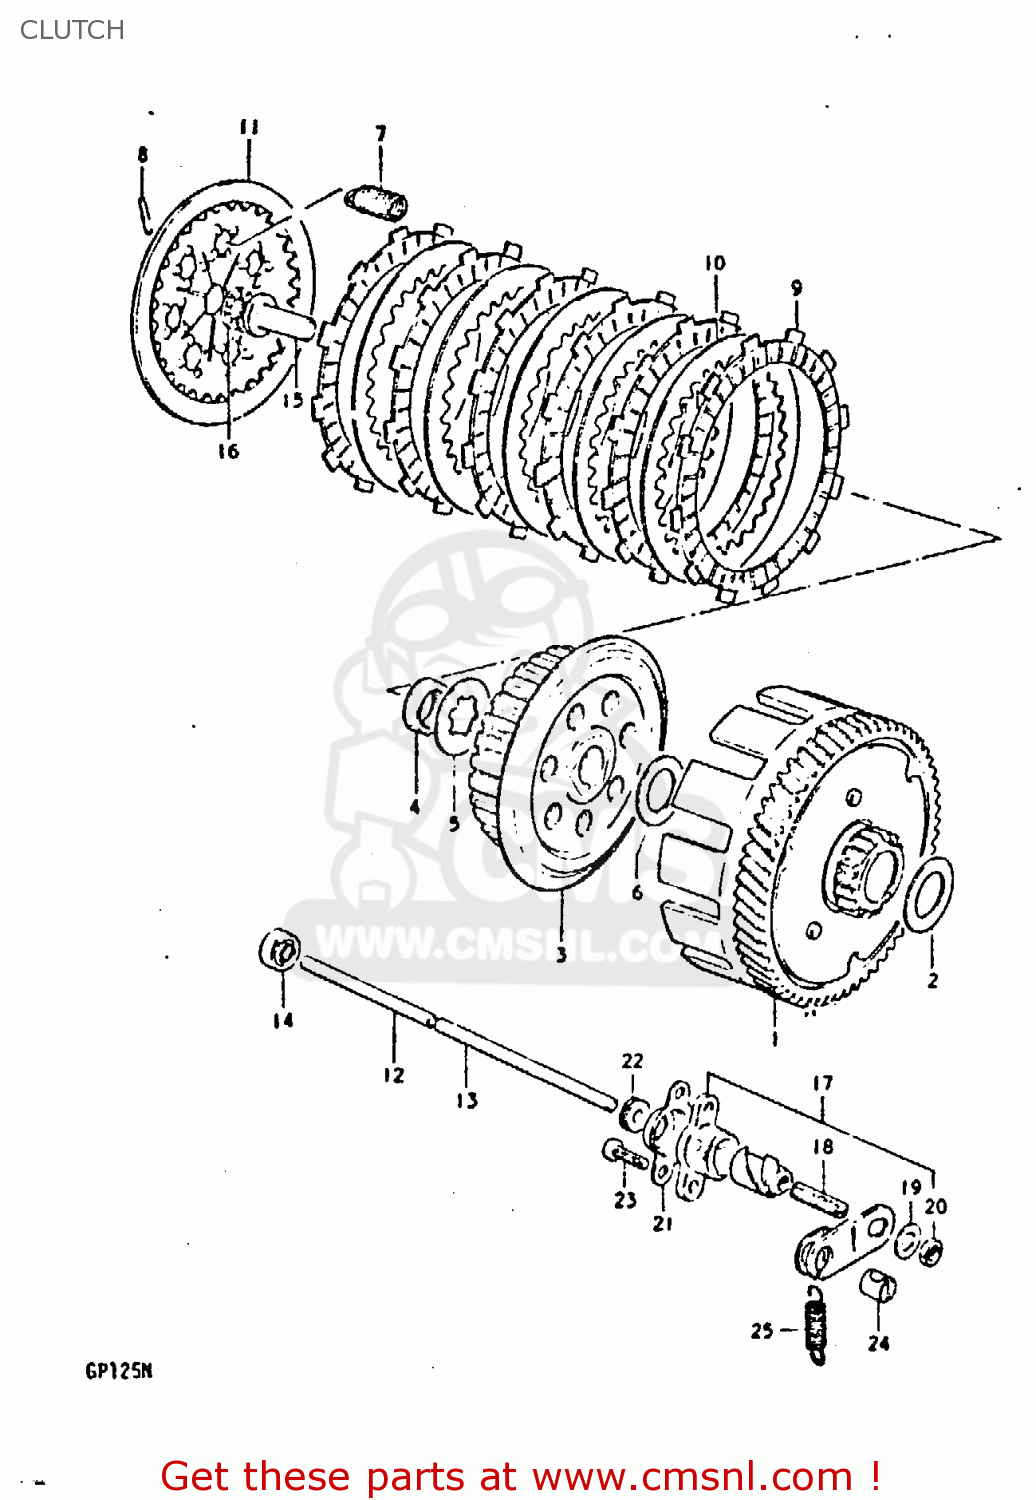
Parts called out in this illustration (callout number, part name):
1	GEAR ASSY, PRIMARY DRIVEN
2	WASHER
3	HUB,CLUTCH SLEEVE
4	NUT
5	WASHER,LOCK
6	WASHER
7	SPRING
8	PIN(2.5X19.8)
9	PLATE,CLUTCH DRIVE
10	PLATE,CLUTCH DRIVEN (NAS)
11	PLATE,CLUTCH PRESSURE
12	ROD,CLUTCH PUSH
13	ROD,CLUTCH PUSH
14	OIL SEAL
15	PIECE, PUSH
16	BEARING(10X22X2.8)
17	SCREW ASSY, RELEASE
18	SCREW
19	WASHER(6.5X16X1.2)
20	NUT 6MM
21	COVER,CLUTCH RELEASE SCREW
22	SEAL,DUST(5.3X13X5)
23	SCREW
24	PIECE,RELEASE ARM END
25	SPRING
